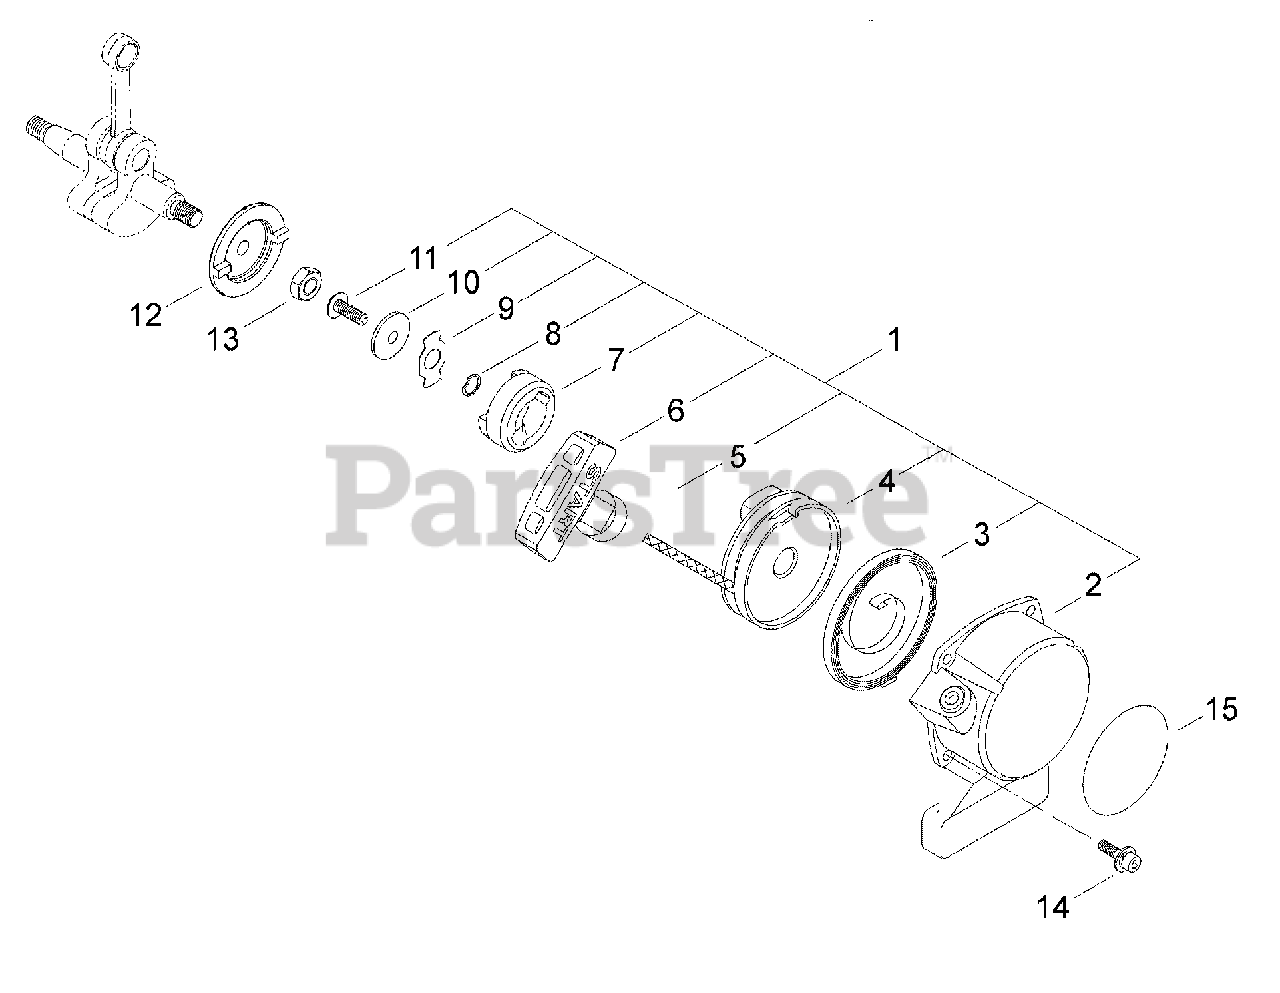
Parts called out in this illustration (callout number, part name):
1	STARTER ASSY, RECOIL
2	CASE, RECOIL STARTER
3	SPRING, RECOIL
4	REEL, ROPE
5	ROPE, STARTER
6	GRIP, STARTER
7	PAWL, STARTER
8	WASHER, WAVE
9	RETAINER
10	WASHER 5 MM
11	SCREW 5 MM
12	PULLEY, STARTER
13	NUT M8×1
14	BOLT M4×16
15	LABEL, SWISHER E4
